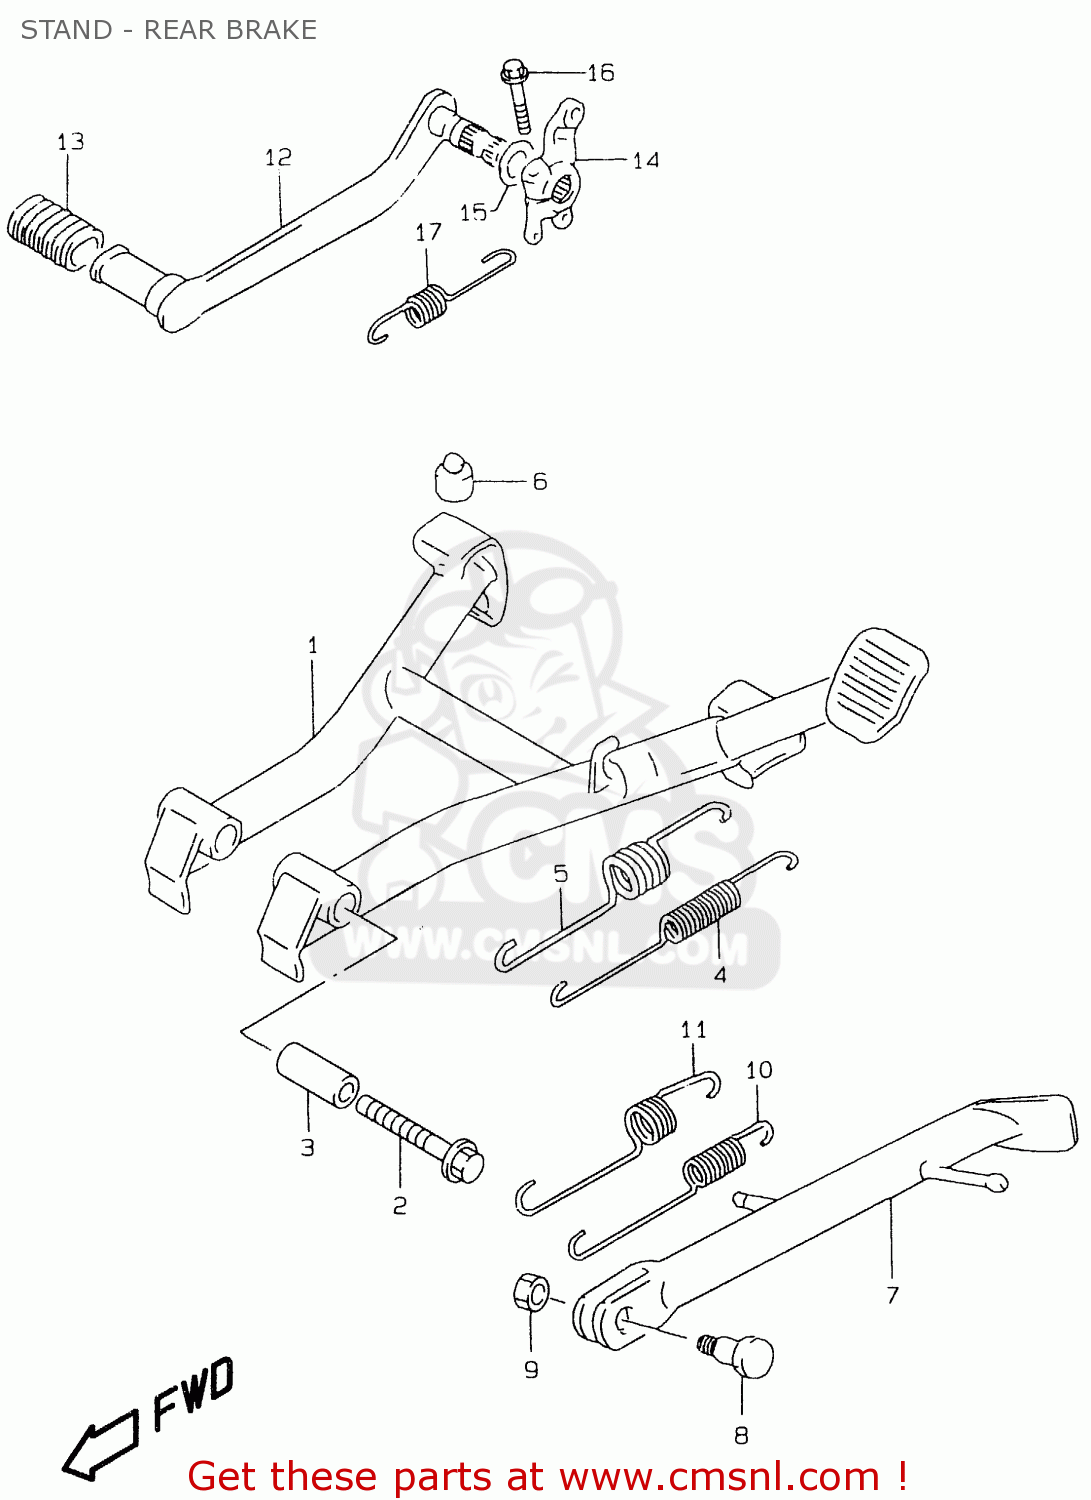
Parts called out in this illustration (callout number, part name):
1	STAND,CTR
2	BOLT
3	SPACER(10X16X38.8)
4	SPRING
5	SPRING OUTER
6	CUSHION
7	STAND,PROP(BLACK)
8	BOLT(10X34)
9	NUT
10	SPRING
11	SPRING
12	PEDAL,BRAKE
13	RUBBER,PEDAL
14	ARM,BRAKE ROD
15	WASHER,BRAKE PEDAL
16	BOLT
17	SPRING
